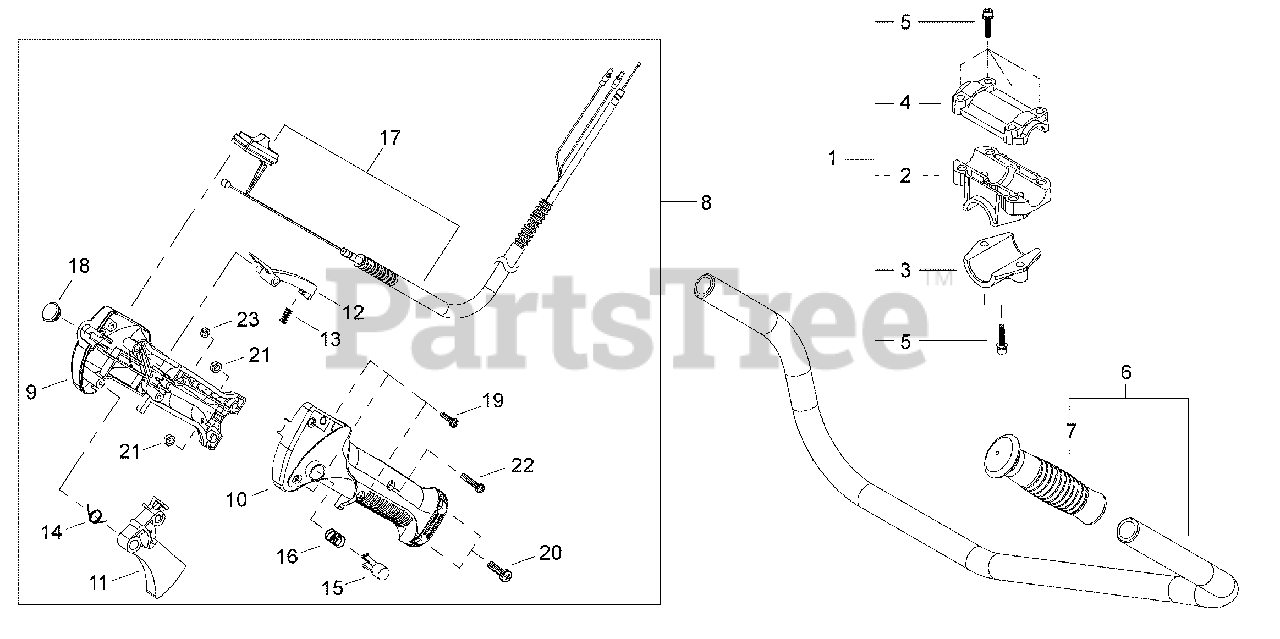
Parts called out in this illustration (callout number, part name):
1	BRACKET KIT, HANDLEBAR
2	BRACKET, LOWER HANDLEBAR
3	BRACKET, MOUNTING
4	BRACKET, UPPER HANDLEBAR
5	BOLT M5×25
6	HANDLEBAR ASSY
7	GRIP
8	GRIP ASSY, THROTTLE
9	CONTROL HANDLE - RIGHT
10	CONTROL HANDLE - LEFT
11	TRIGGER, THROTTLE
12	LOCKOUT, THROTTLE
13	SPRING, COMPRESSION
14	SPRING, TORSION
15	BUTTON, THROTTLE LOCK
16	SPRING, COMPRESSION
17	CABLE ASSY, CONTROL
18	PLUG, RUBBER
19	SCREW, TAPPING 4×16
20	SCREW M5×20
21	NUT M5
22	SCREW M4×23
23	NUT M4
